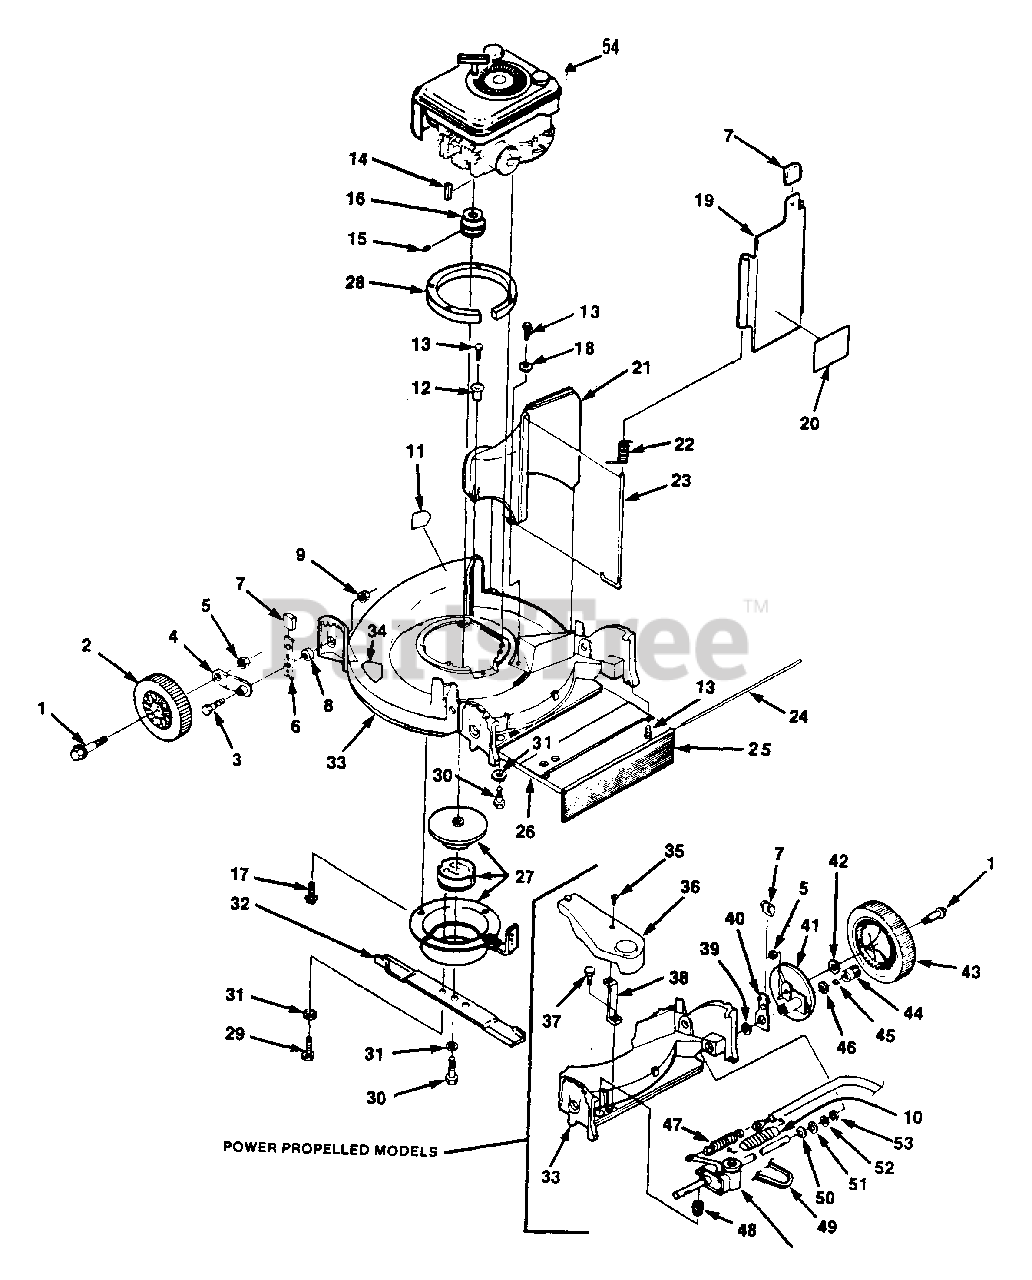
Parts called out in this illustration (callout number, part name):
1	AXLE - ASSY
2	WHEEL ASSY
3	BOLT - 5/16×18
4	ARM - WHEEL ADJUSTING
5	NUT - 3/8-24
6	INDEXING SPRING & PIN ASSY
7	KNOB
8	SPACER
9	NUT - 5/16-18 -- FLANGE
10	COVER, SPRING
11	LABEL - WARNING
12	EYELET
13	SCREW - 1/4-20×3/4" -- HEX CAP
14	KEY
15	SCREW, SET
16	PULLEY - DRIVE
17	SCREW - 5/16-18
18	WASHER - 1/4"
19	DOOR, CHUTE
20	LABEL - DOOR
21	CHUTE, DISCHARGE
22	SPRING
23	PIN, HINGE
24	ROD, DRAG FLAP
25	FLAP, DRAG
26	COVER, REAR
27	BLADE/BRAKE/CLUTCH
28	RING, ENGINE
29	SCREW - 3/8-16×1"
30	SCREW - 3/8-24×2"
31	WASHER, LOCK 3/8
32	BLADE - 21"
33	DECK ASSEMBLY
34	LABEL - FOOT PAD
35	SCREW - 1/4-20×3/4" -- HEX HEAD
36	COVER, DRIVE
37	SCREW - 10-16×1/2" -- HEX CAP
38	SUPPORT-BELT COVER
40	INDEXING SPRING & PIN ASSY
41	DRIVE WHEEL SUPPORT ASSY
42	WASHER, FLAT
43	WHEEL ASSY
44	PINION - R.H.
44	PINION, L.H.
45	PAWL
46	WASHER, FLAT
47	SPRING
49	BELT, DRIVE
50	RING - EATON
52	WASHER
53	WASHER
54	ENGINE - M14V-B1ZO
